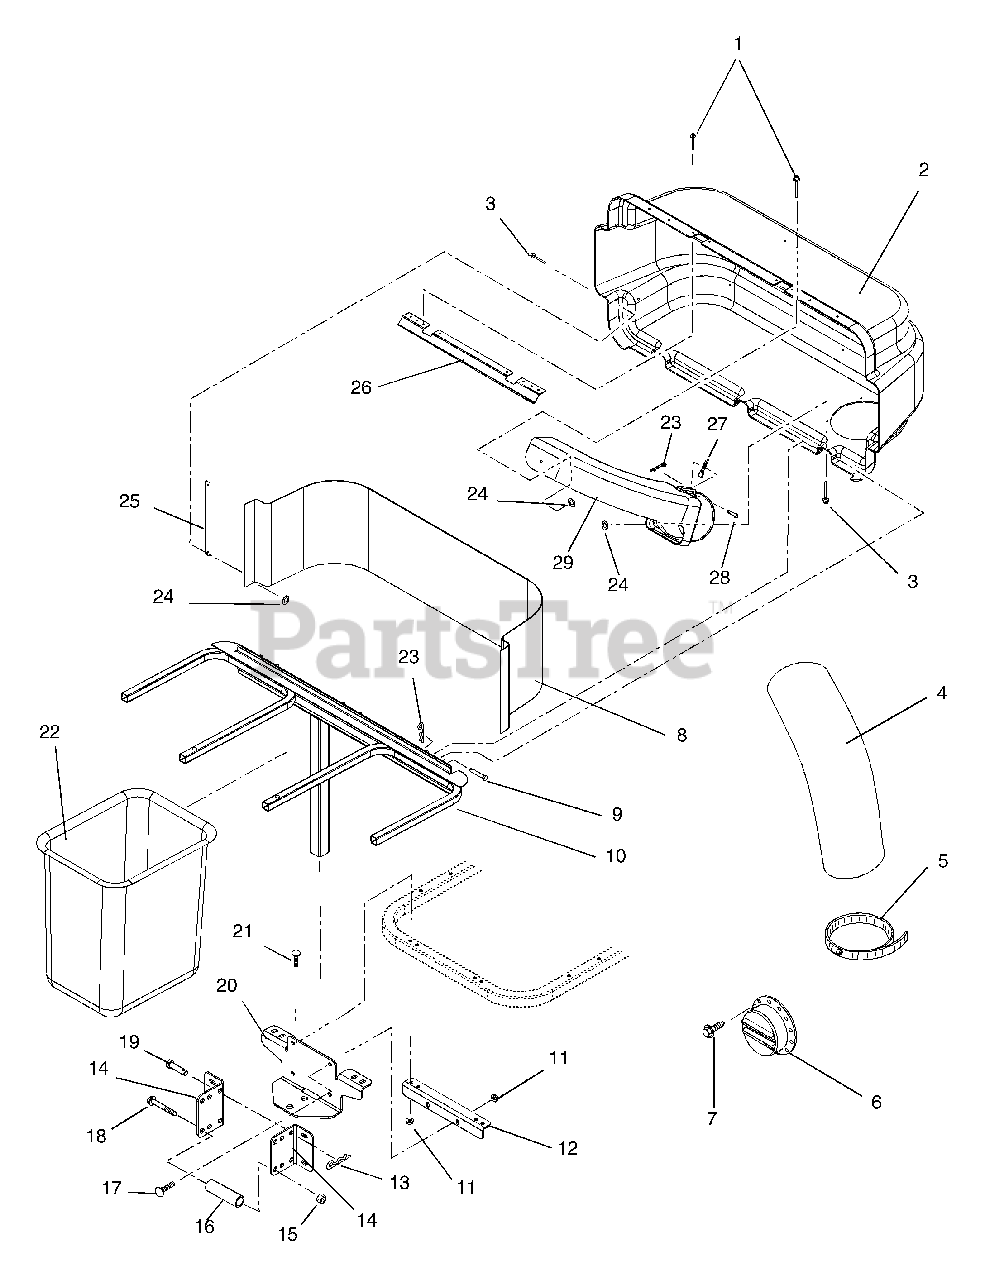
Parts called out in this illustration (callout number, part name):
1	Rivet-Pop .187 x .402
2	Cover,Bagger with Decal
3	Rivet-Pop .187X.527
4	Hose 7 x 45
5	Clamp-Hose Worm 2.13/8.62 x .56
6	Deflector, Exhaust
7	Screw-Tapping 8-32X.38 Slotted Hex Washer Head
8	Screen, Bagger
9	Pin-Clevis .368/.373 x 3.25
10	Weldment, Bagger Frame
11	Nut-Locking-Top-Flange .38-16
12	Bracket,Angle
13	Pin-Hair-External .12 x .31 x 2.37
14	Bracket, Bagger Mount
15	Nut-Locking-Top-Flange .50-13
16	Spacer, Pivot
17	Bolt-Round Head Square Neck .38-16 x 1.25 Grade 5
18	Bolt-Hex .50-13 x 3.00 Grade 5
19	Pin-Clevis .494 x 2.50
20	Trailer Hitch with Decals
21	Bolt-Round Head Square Neck .38-16 x 2.50-Grade 5
22	Grass Bagger Basket
23	Pin-Hair
24	Washer-Flat-STL .219 x .50 x .049
25	Strap, Cover
26	Latch, Cover
27	Indicator, Flow
28	Pin-Clevis .31 x 2.62 Grade 5
29	Boot, Upper
